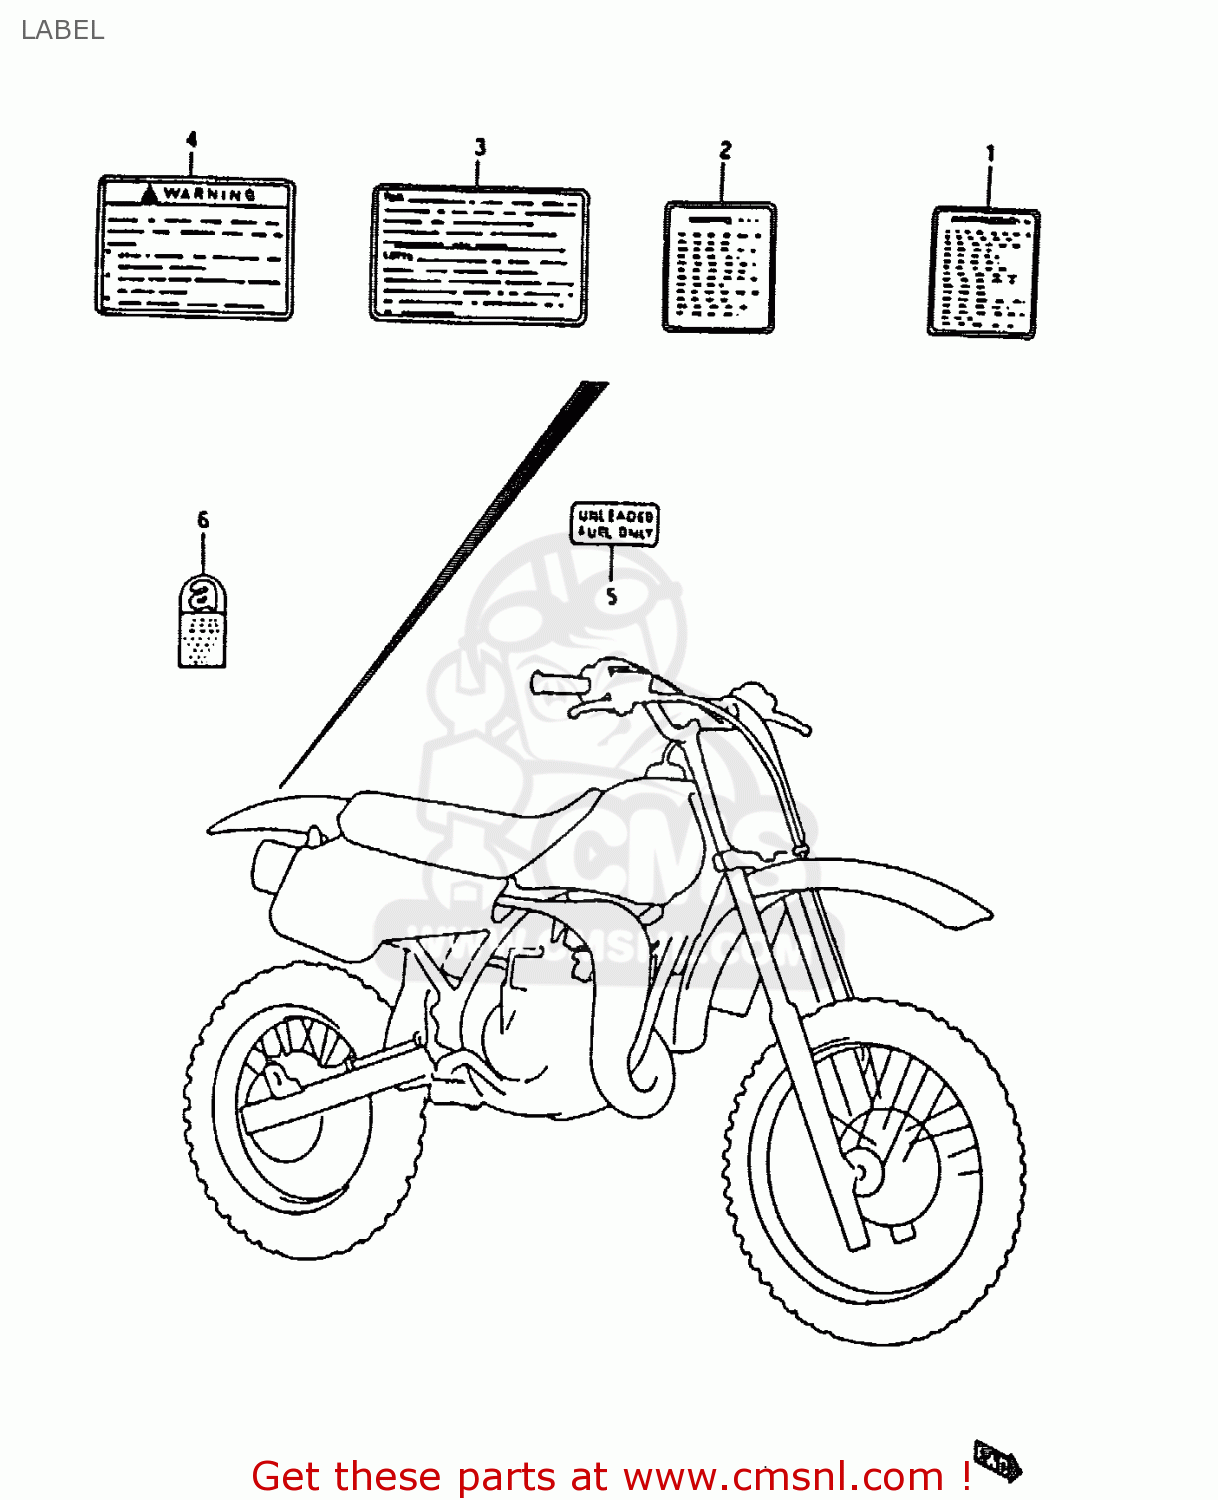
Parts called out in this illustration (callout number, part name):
1	LABEL,WARNING
2	LABEL,WARNING
3	LABEL,WARNING
4	LABEL
5	LABEL,UNLEADED FUEL
6	LABEL,ASBESTOS WARNING
7	MANUAL, OWNER'S
